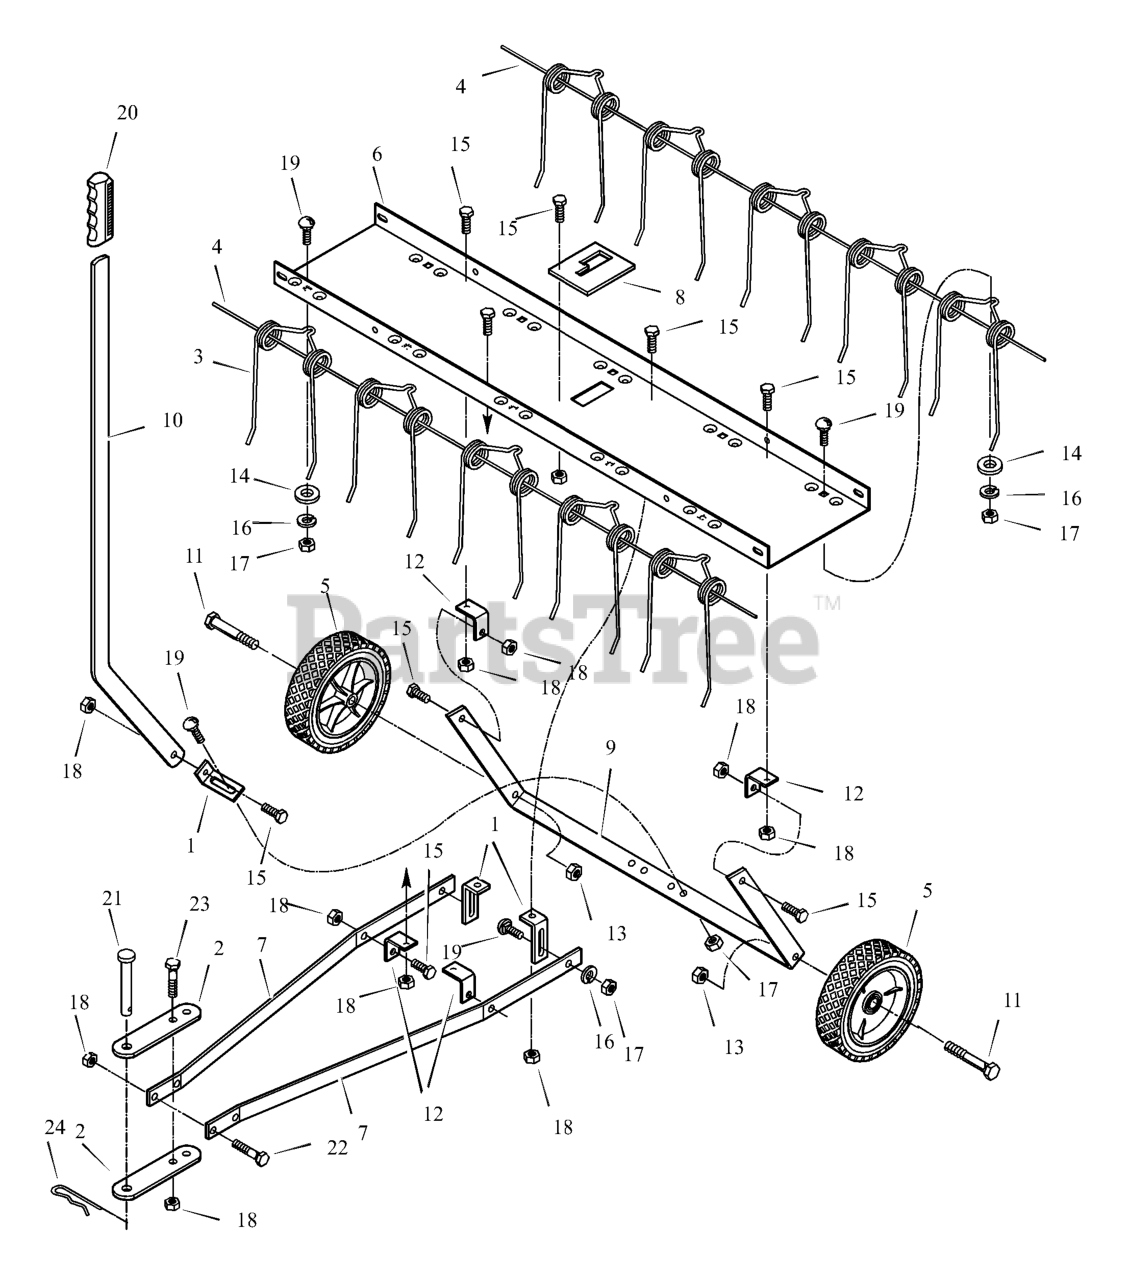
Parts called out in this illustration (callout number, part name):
1	Hitch Arm Mount Bracket
2	Hitch Bracket
3	Spring Tine
4	Spring Alignment Wire
6	Tine Shield
7	Hitch Mount Arm
8	Lift Plate
9	Axle Bracket
10	Lift Handle
11	Shoulder Bolt
12	Angle Bracket
13	Hex Lock Nut M10
14	Flat Washer M8
15	Hex Bolt M8X20
16	Lock Washer M8
17	Hex Nut M8
18	Hex Lock Nut M8
19	Carriage Bolt M8X25
20	Handle Grip
21	Hex Bolt M8X50
22	Hex Bolt M8X30
23	Hitch Pin M8
24	Hair Cotter Pin
